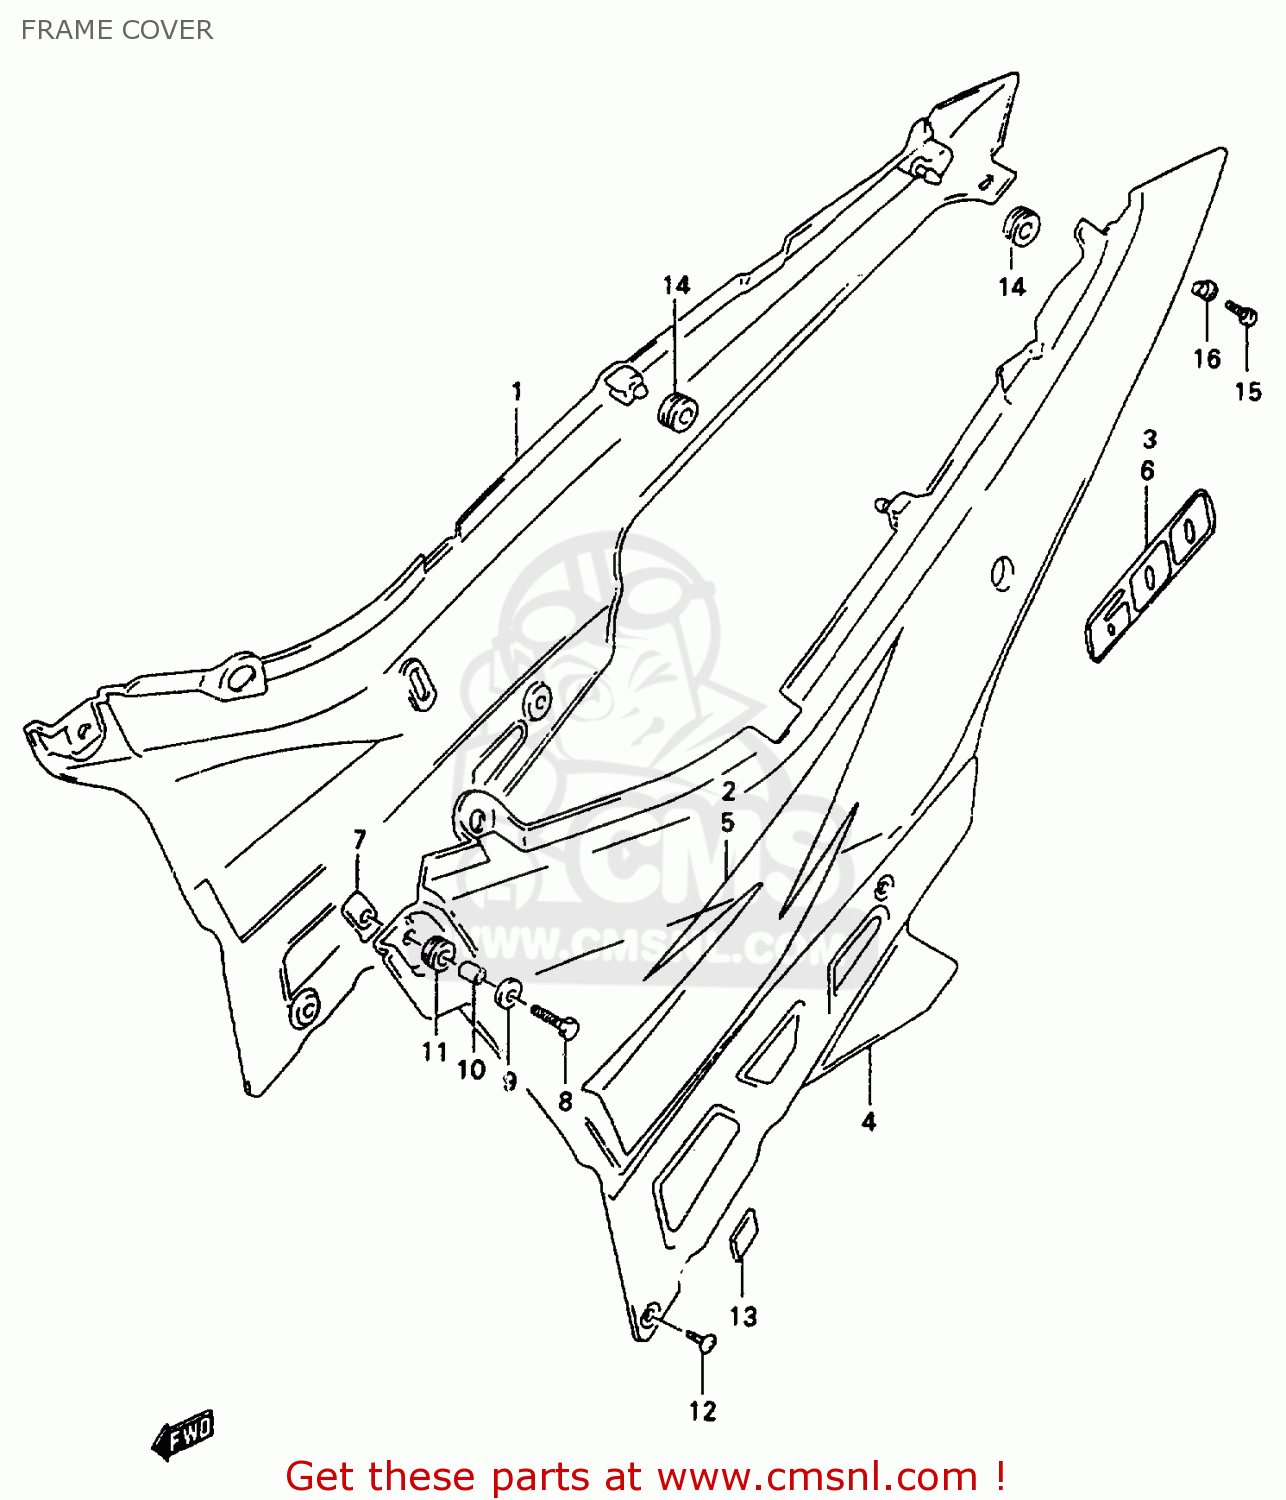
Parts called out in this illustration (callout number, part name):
1	COVER COMP,FRAME,RIGHT
2	TAPE,FRAME COVER,RIGHT
3	EMBLEM,FRAME COVER
4	COVER,FRAME,L
5	TAPE,FRAME COVER,LEFT
6	EMBLEM,FRAME COVER
7	PLATE,FRAME COVER
8	SCREW(6X20)
9	WASHER(6.5X18X1.6)
10	SPACER(6.5X9X9)
11	CUSHION
12	SCREW(5X15.3)
13	CUSHION,FRAME COVER
14	CUSHION
15	SCREW 5X12
16	WASHER
